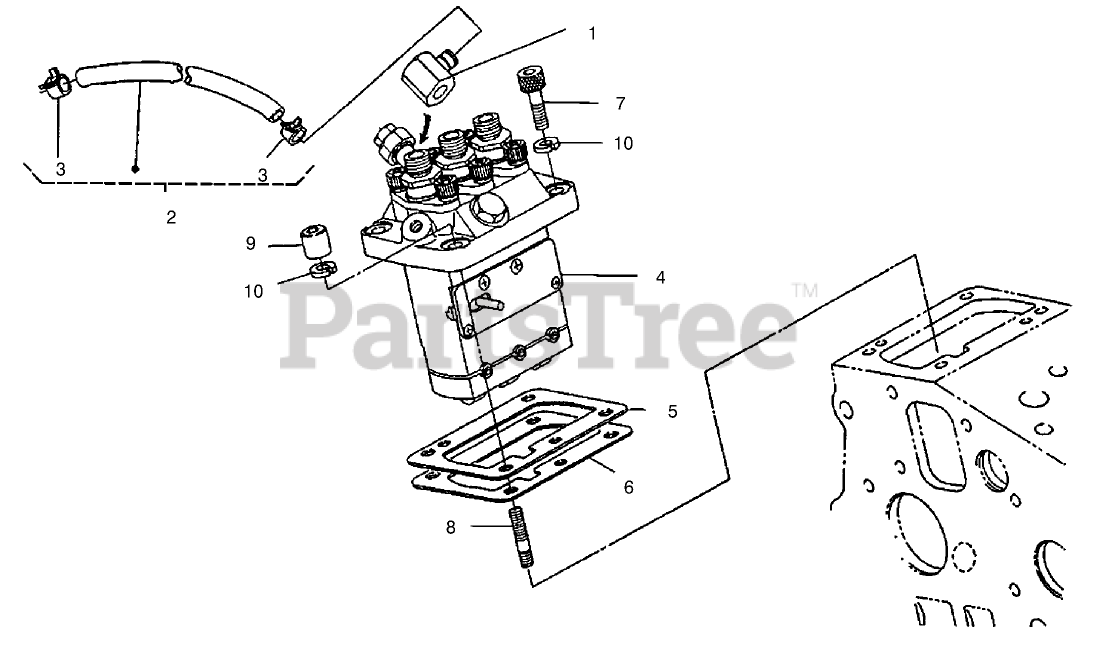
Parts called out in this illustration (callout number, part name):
1	JOINT-EYE
2	FUEL PIPE ASM
3	BAND-PIPE
4	INJECTION PUMP ASM
4	ASSY PUMP, INJ. (S/N 489915 or lower)
5	SHIM-PUMP, INJECTION
5	SHIM-INJECTION (0.20MM)
6	SHIM-PUMP, INJECTION
6	SHIM-INJECTION (0.25MM)
6	SHIM-INJECTION (0.30MM)
7	BOLT-HSH
9	NUT-CAP
10	WASHER-SPRING
